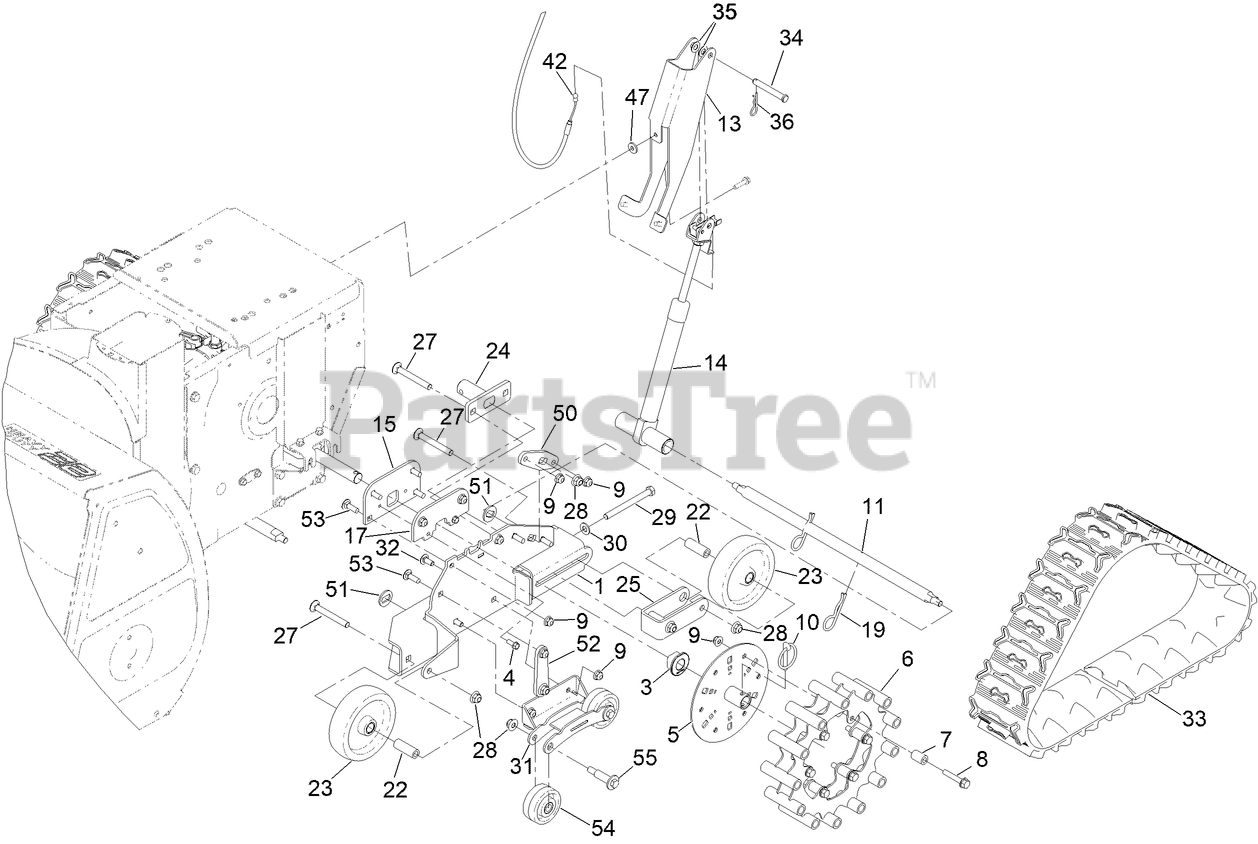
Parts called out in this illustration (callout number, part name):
1	SUPPORT-TRACK, ASM LH
3	BUSHING-AXLE
4	SCREW-HWH
5	HUB-DRIVE, WELD ASM
6	WHEEL-DRIVE, WELD ASM
7	TUBE-SUPPORT
8	SCREW-HHF
9	NUT-HF
10	KLIK PIN ASM
11	BAR-PIVOT
13	MOUNT-LIFT
14	STRUT-HEIGHT
15	MOUNT-BUSHING, REAR
17	MOUNT-BUSHING, FRONT
19	PIN-HAIR
22	BUSHING-TENSIONER
23	WHEEL-BOGEY
24	TENSIONER, WELDED
25	YOKE-BOGEY
27	BOLT-CARRIAGE
28	NUT-HF, NI
29	SCREW-HH
30	WASHER-FLAT
31	SUPPORT-WHEEL, ASM
32	BOLT-CARR
33	TRACK-SNOW
34	PIN-CLEVIS
35	WASHER-THRUST
36	PIN-HAIR
42	CABLE-HEIGHT
47	SPACER-MOUNT
50	PLATE-BAR, PIVOT
51	WASHER-SPECIAL, D
52	PLATE-SUPPORT
53	BOLT-CARR
54	WHEEL-BOGEY
55	BOLT-SHOULDER
